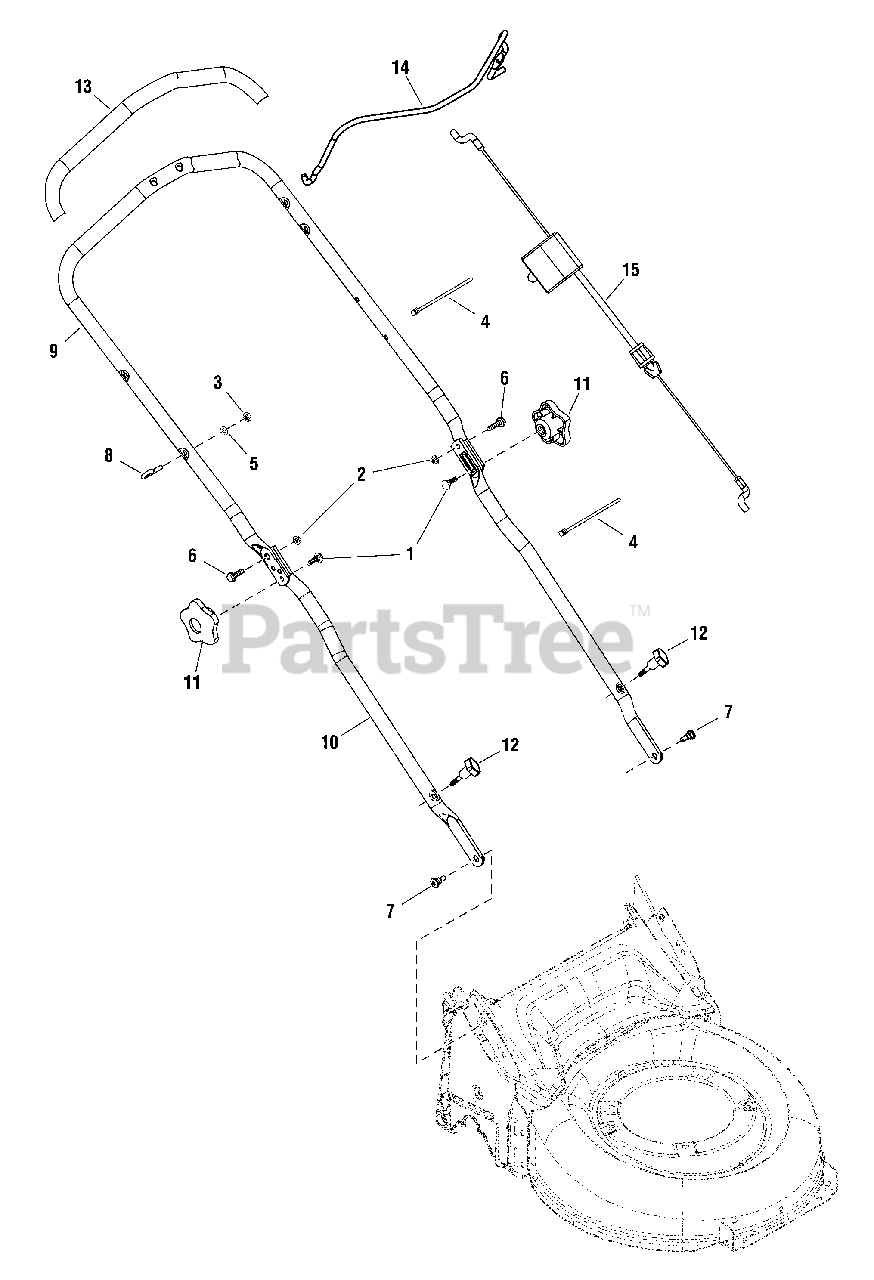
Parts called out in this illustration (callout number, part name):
1	BOLT, 5/16-18 x 1 G5
2	NUT, Nylock Flanged, 1/4-20
3	NUT, Nylock, M6
4	CABLE CLIP
5	WASHER, A6.4
6	SCREW, 1/4-20
7	BOLT, Shoulder
8	BOLT, Eye
9	HANDLE, Upper
10	HANDLE, Lower
11	WING KNOB, 5/16-18
12	WING KNOB
15	CABLE, Control
